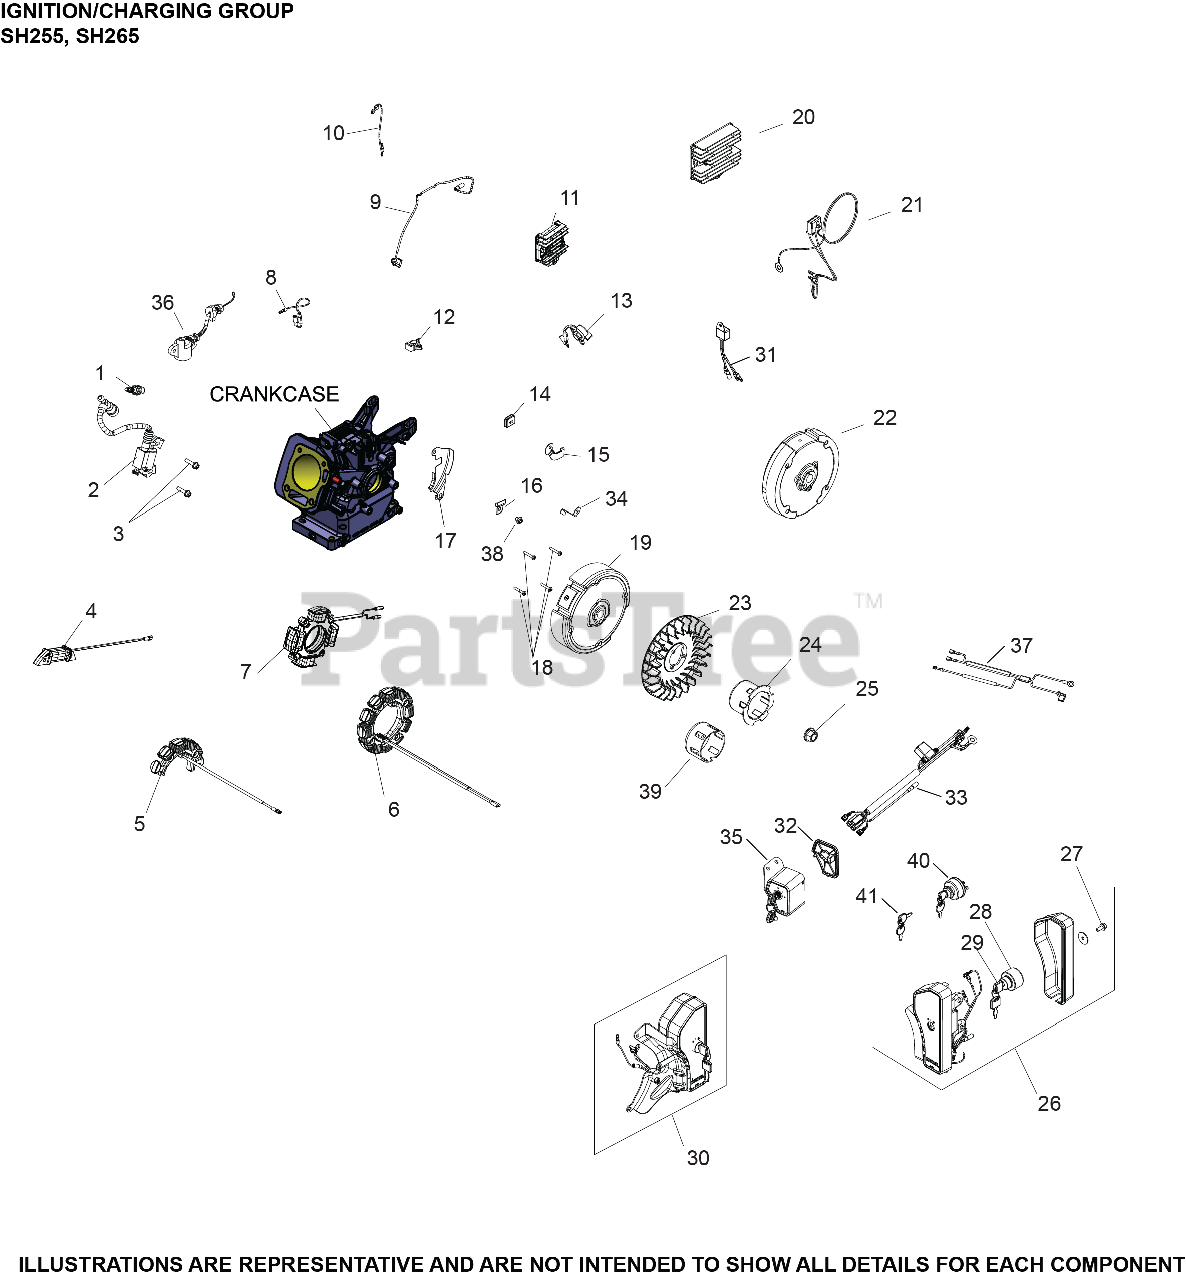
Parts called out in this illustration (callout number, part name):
1	PLUG, SPARK (STD)
2	MODULE, IGNITION
3	SCREW, M6 X 25 USE 25 086 436-S
12	CLIP, WIRE HARNESS
13	SWITCH, IGNITION
19	FLYWHEEL ASSEMBLY
23	FAN, FLYWHEEL
25	NUT, FLYWHEEL (W/SERRATIONS)
30	CLIP, WIRE HARNESS - DISCONTINUED
39	STARTER CUP
